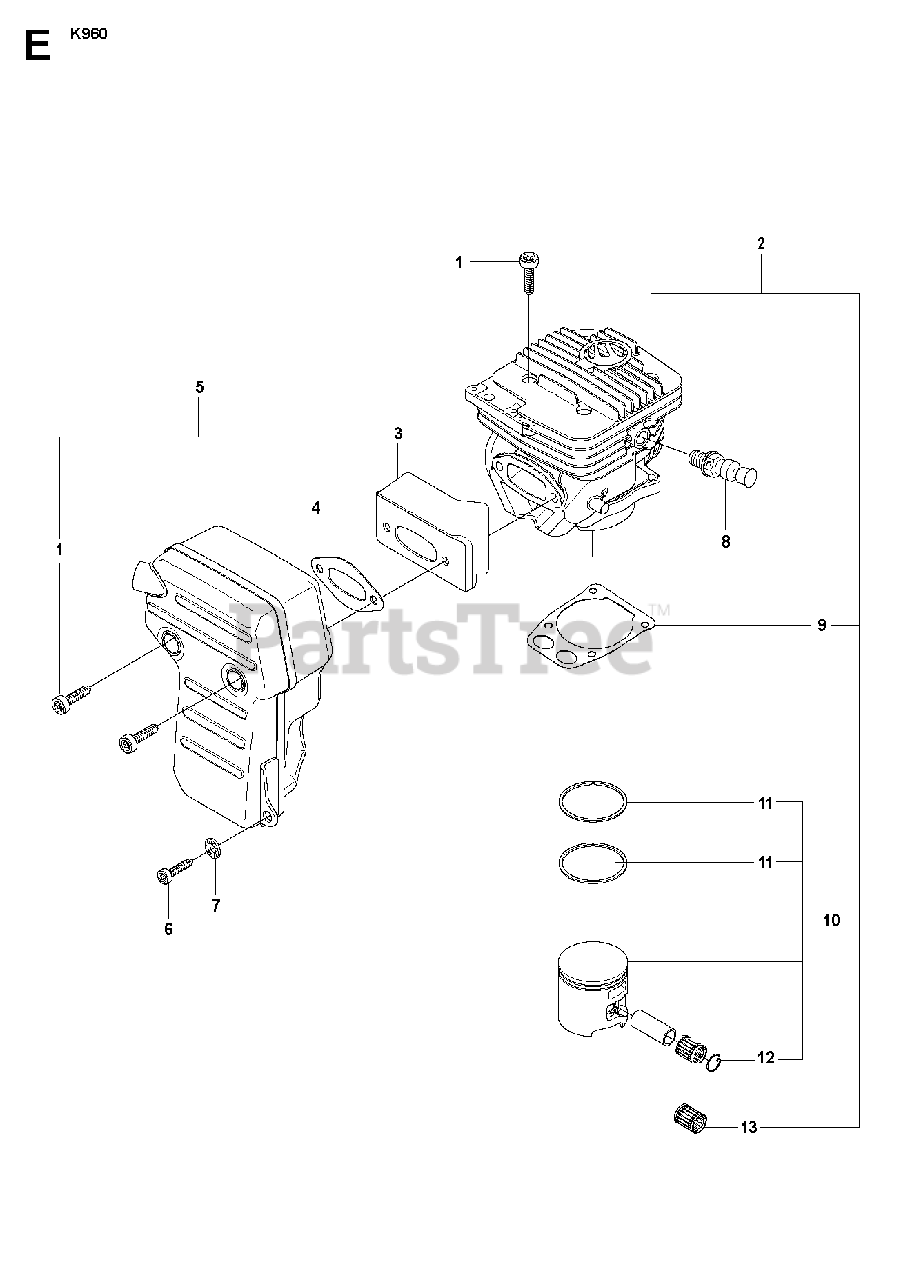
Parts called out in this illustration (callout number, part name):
1	SCREW ITXSCM
2	CYLINDER ASSYIncl. 9, 10, 13
3	HEAT DEFLECTOR
4	GASKET
5	MUFFLER ASSYIncl. 1, 4
6	SCREW ITXSCM
8	DECOMPRESSION VALVE
9	GASKET
10	PISTONIncl. 11, 12
13	NEEDLE BEARING
